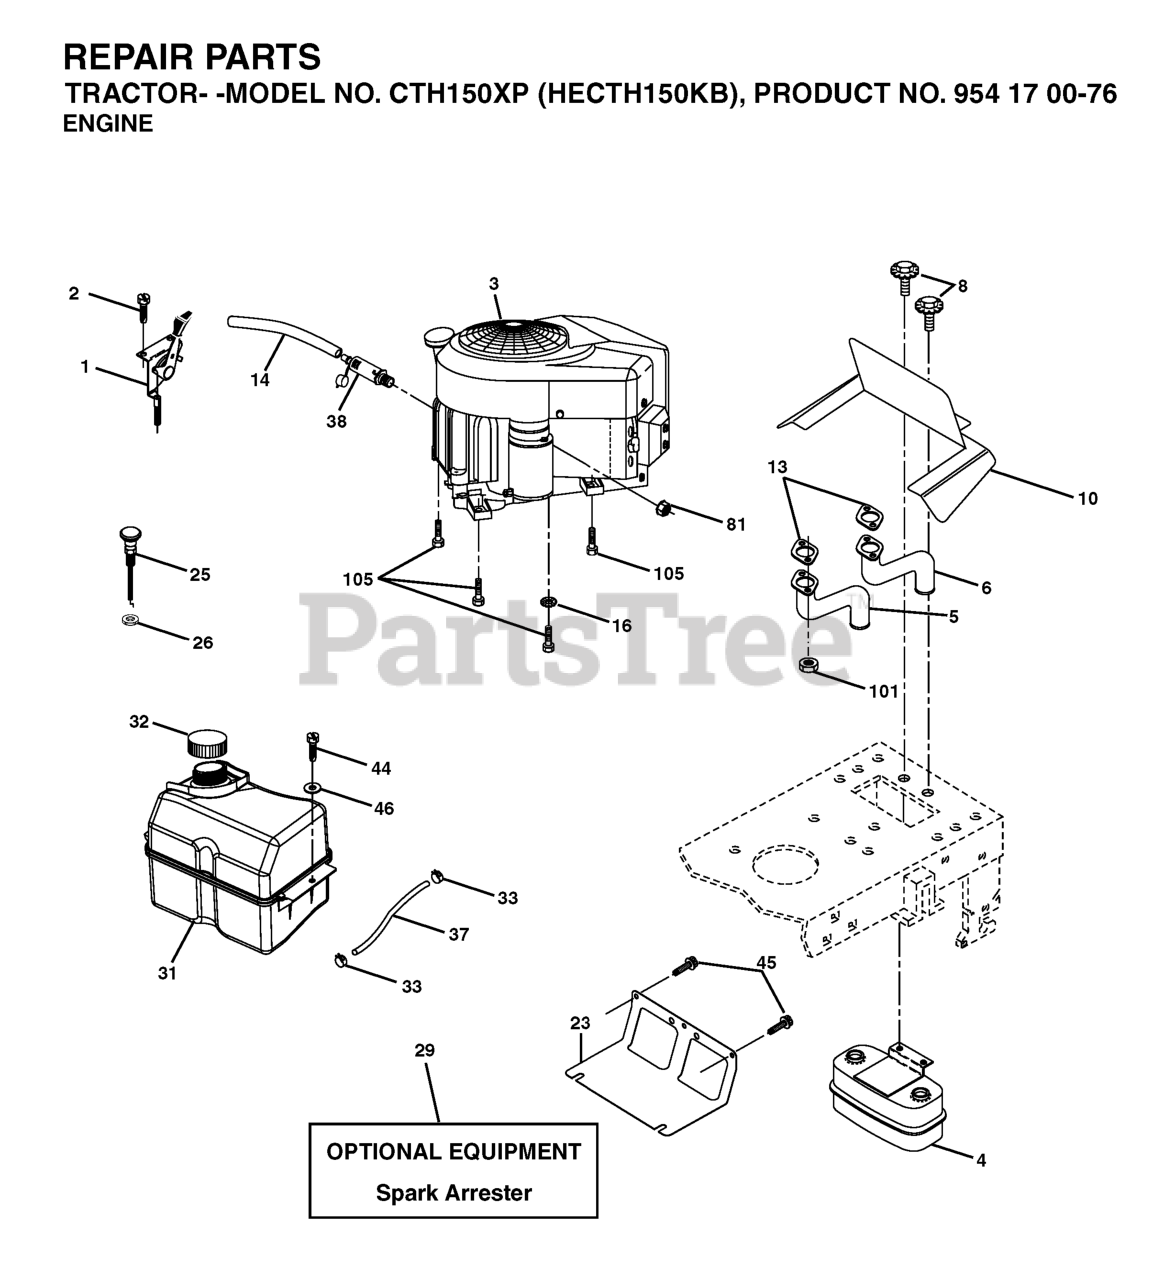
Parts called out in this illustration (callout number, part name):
1	CONTROL, THROTTLE
2	SCREW
4	MUFFLER.TWIN.CYL.LOW.TONE
5	EXHAUST TUBE LH KAWI
6	EXHAUST TUBE RH KAWI
8	BOLT.5/16-18UNCX3/4 W/SEMS.BLK
10	RP SHIELD HEAT MUFFLER
14	TUBE, DRAIN OIL ASM.
16	LOCKWASHER
23	SHIELD.BROWNING.DBR.GUARD
25	CHOKE CONTROL
26	Nut Keps 3/8 - 24 UNF
29	KIT.SPARK ARRESTOR 794945 B&S
31	TANK FUEL
32	FUEL CAP
33	HOSE CLAMP
37	LINE.FUEL.20
40	BUSHING.SNAP.NYL.BLK.
44	SCREW HEXWSHR 1/4-20X3/4
45	SCREW, 3/8-16X3/4
81	NUT
101	FLANGE NUT
105	SCREW 3/8-16X1
